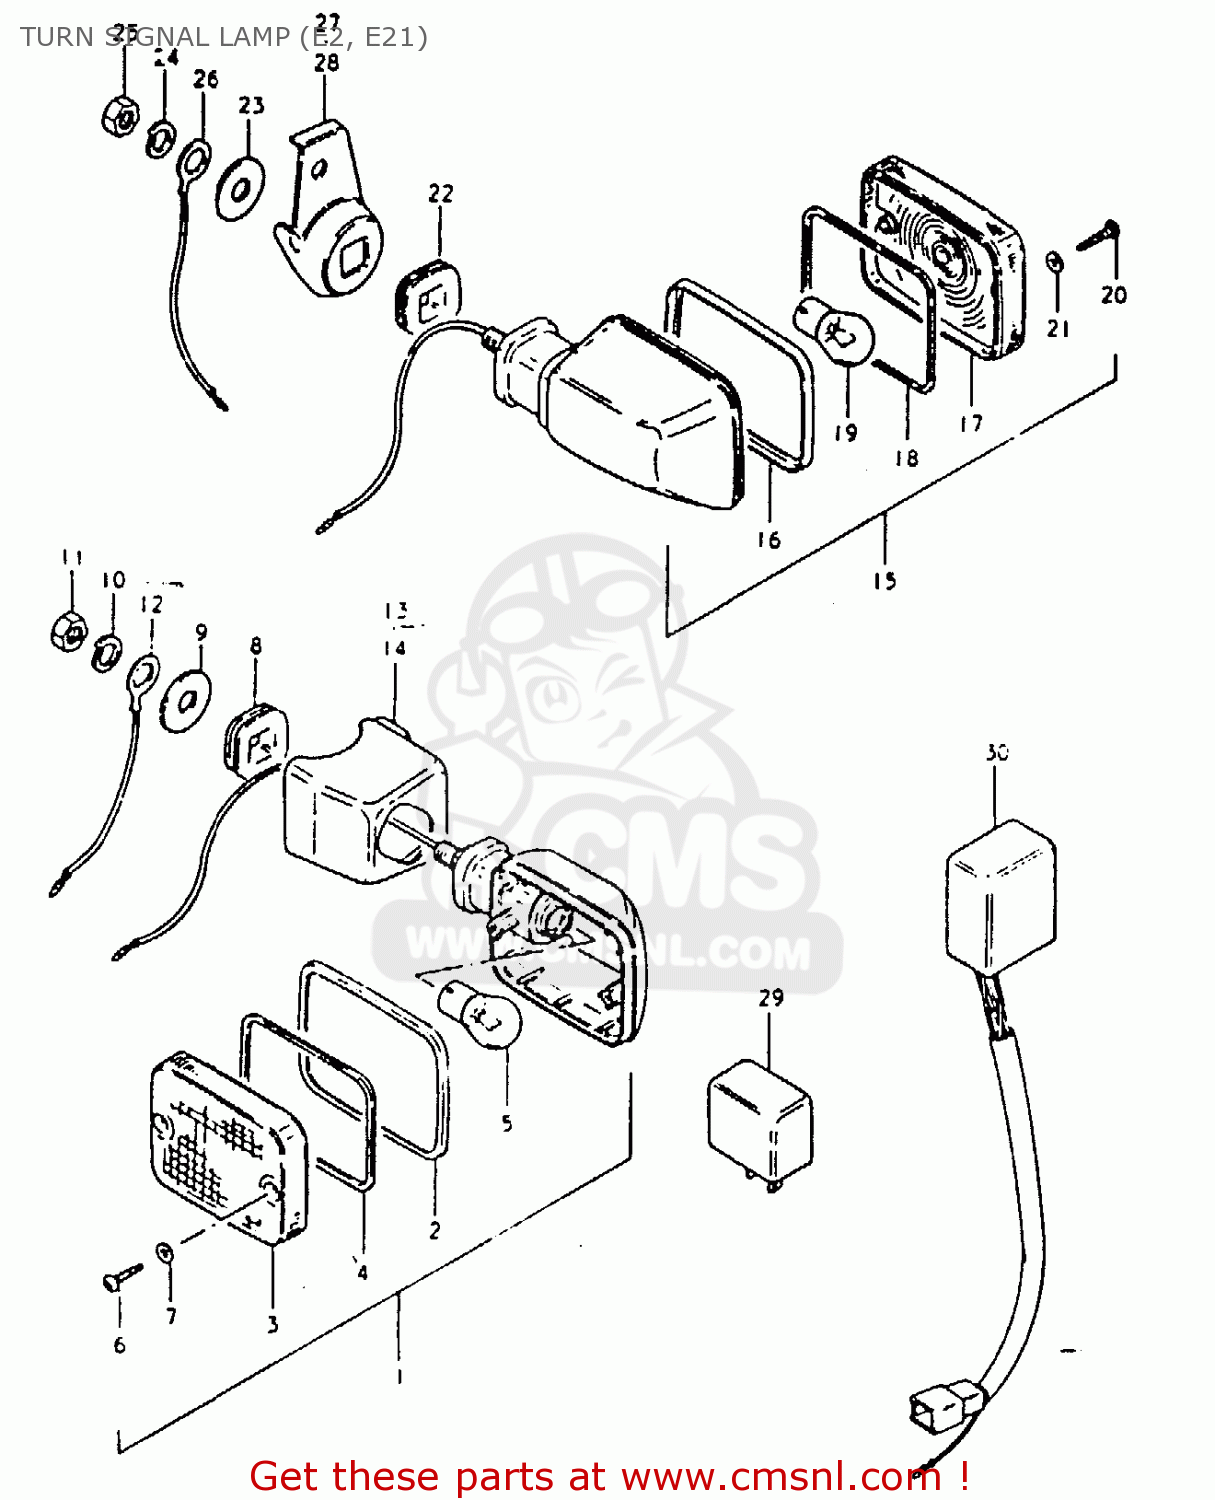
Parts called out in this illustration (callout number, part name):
1	LAMP, FRONT TURN SIGNAL
2	RIM
3	LENS
4	GASKET (NAS)
5	BULB 12V 21W
6	SCREW
7	GASKET (NAS)
8	CUSHION
9	WASHER (10.5X30X2.3)
10	LOCK WASHER
11	NUT
12	WIRE,TURN SIGNAL LEAD
13	COVER,TURN SIGNAL BRACKET
14	COVER,TURN SIGNAL BRACKET
15	LAMP, REAR TURN SIGNAL
16	RIM
17	LENS
18	GASKET (NAS)
19	BULB 12V 21W
20	SCREW
21	GASKET (NAS)
22	CUSHION
23	WASHER (10.5X30X2.3)
24	LOCK WASHER
25	NUT
26	LEAD WIRE,EARTH
27	BRACKET,REAR TURN SIGNAL
28	BRACKET,REAR TURN SIGNAL
29	RELAY ASSY,TURNSIGNAL
30	UNIT,TURN SIGNAL CONTROL
